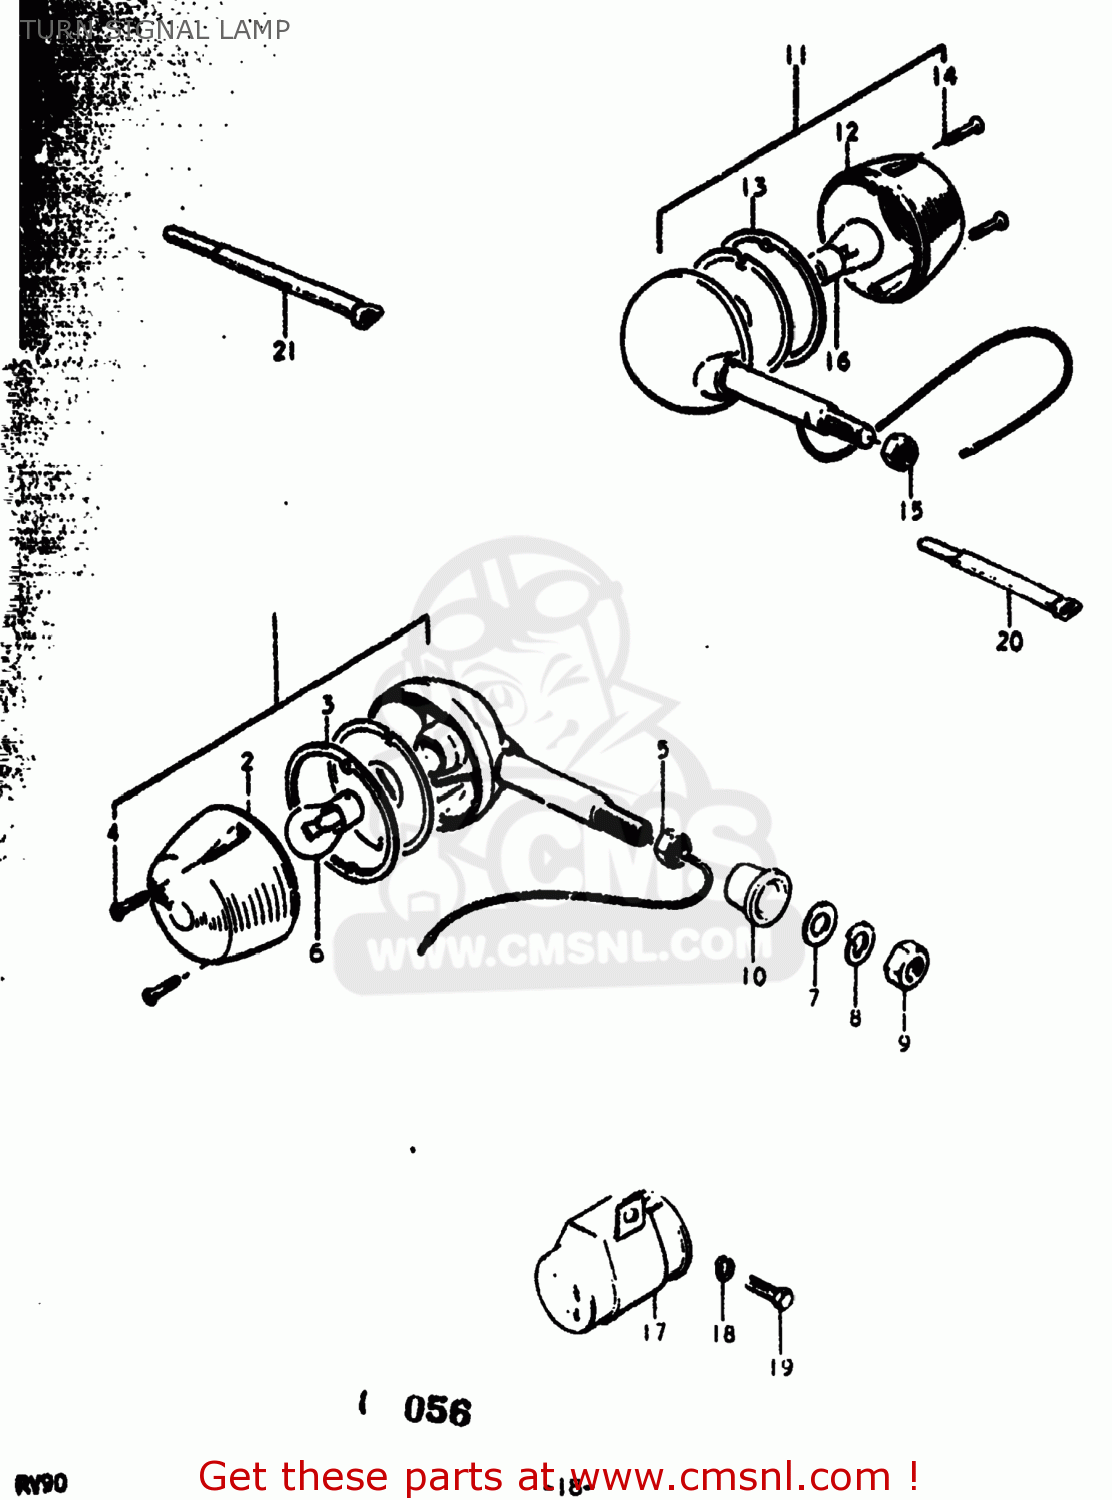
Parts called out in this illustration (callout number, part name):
1	LAMP ASSEMBLY,FRONT TURN SIGNAL
2	LENS,TURNSIGNAL
3	GASKET,TURNSIGNAL LENS (NAS)
4	SCREW
5	NUT
6	BULB(6V17W,STANLEY,A4513A)
7	WASHER
8	LOCK WASHER
9	NUT
10	COVER,FRONT TURN SIGNAL BRACKET
11	LAMP ASSY,RR TURNSIGNAL
12	LENS,TURNSIGNAL
13	GASKET,TURNSIGNAL LENS (NAS)
14	SCREW
15	NUT
16	BULB(6V17W,STANLEY,A4513A)
17	RELAY,TURN SIGNAL
18	LOCK WASHER
19	BOLT
20	CLAMP
21	CLAMP
